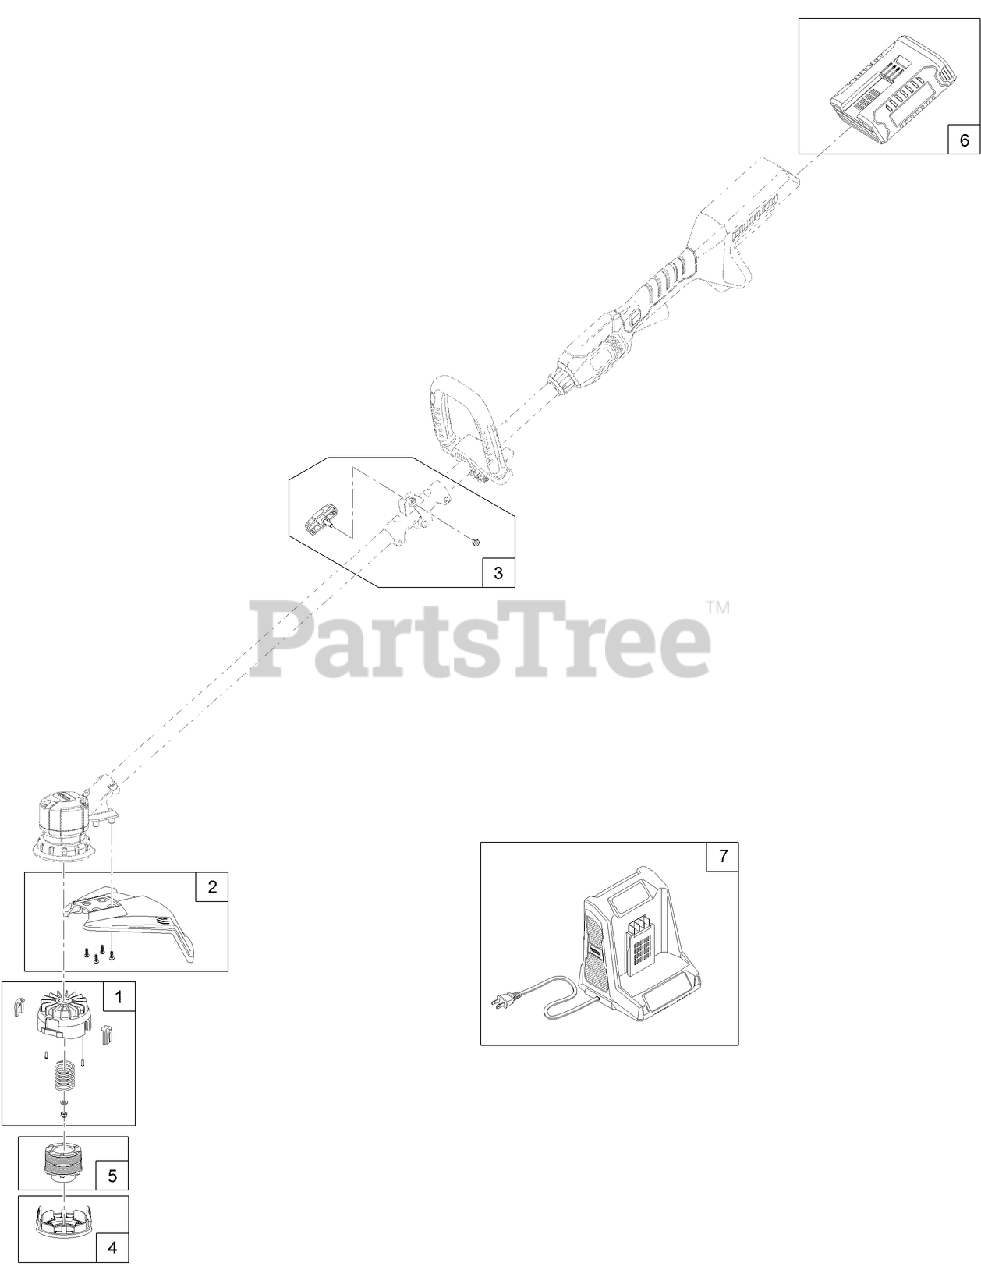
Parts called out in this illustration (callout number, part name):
1	HEAD-FEED, BUMP
2	GRASS SHIELD ASM
3	SHAFT CONNECTION HARDWARE KIT
4	RETAINER-CAP, SPOOL
5	3-PK DUAL-LINE SPOOL
6	BATTERY-40V MAX
7	CHARGER-40V MAX
